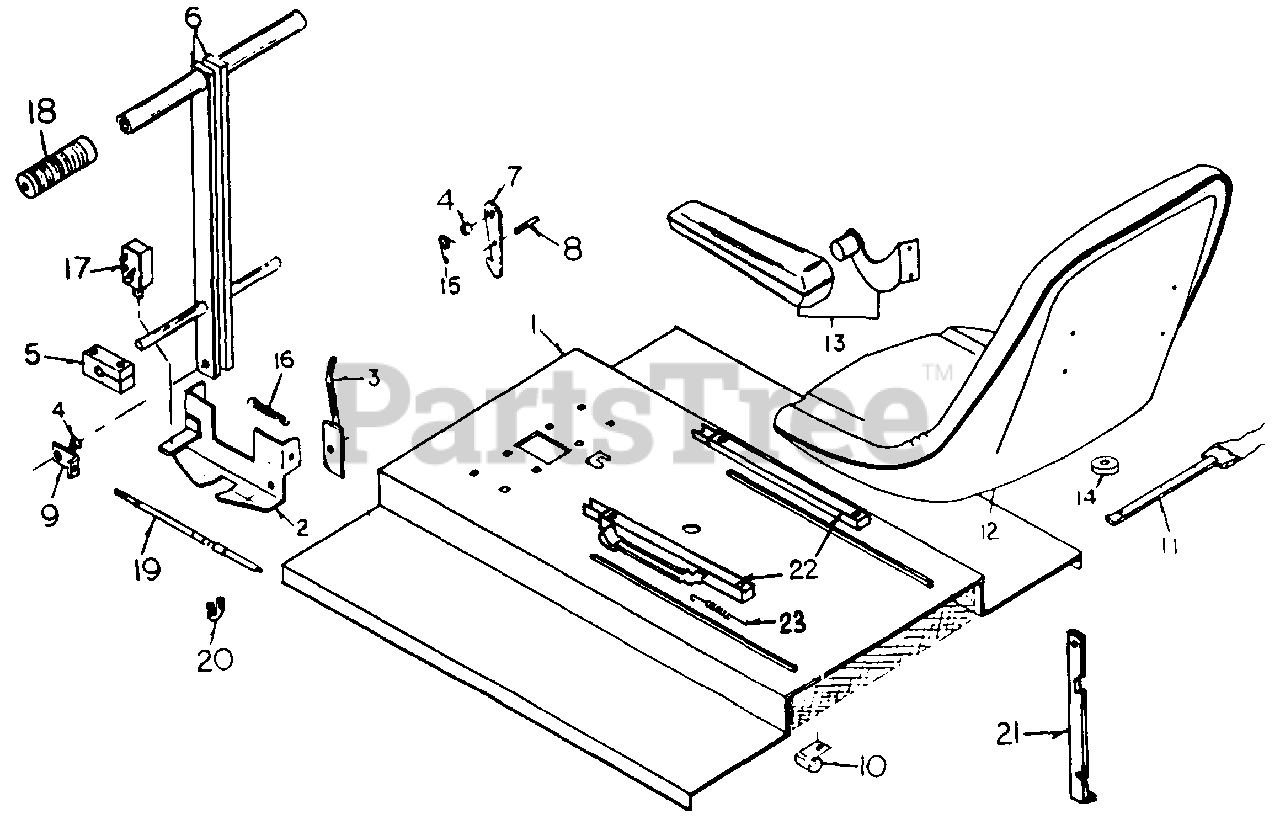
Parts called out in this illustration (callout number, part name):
3	Latch, Lever Lock
4	Bushing
6	Steering Lever
7	Seat Lid Latch
8	Seat Lid Latch Bolt
9	Steering Cable End
10	Seat Lid Harness Retainer
13	Arm Rest Kit
15	Seat Lid Latch Spring
16	Lever Lock Spring
18	Handle Grip
19	Steering Cable
20	Steering Cable Clamp
22	Seat Rail Kit (Pair)
